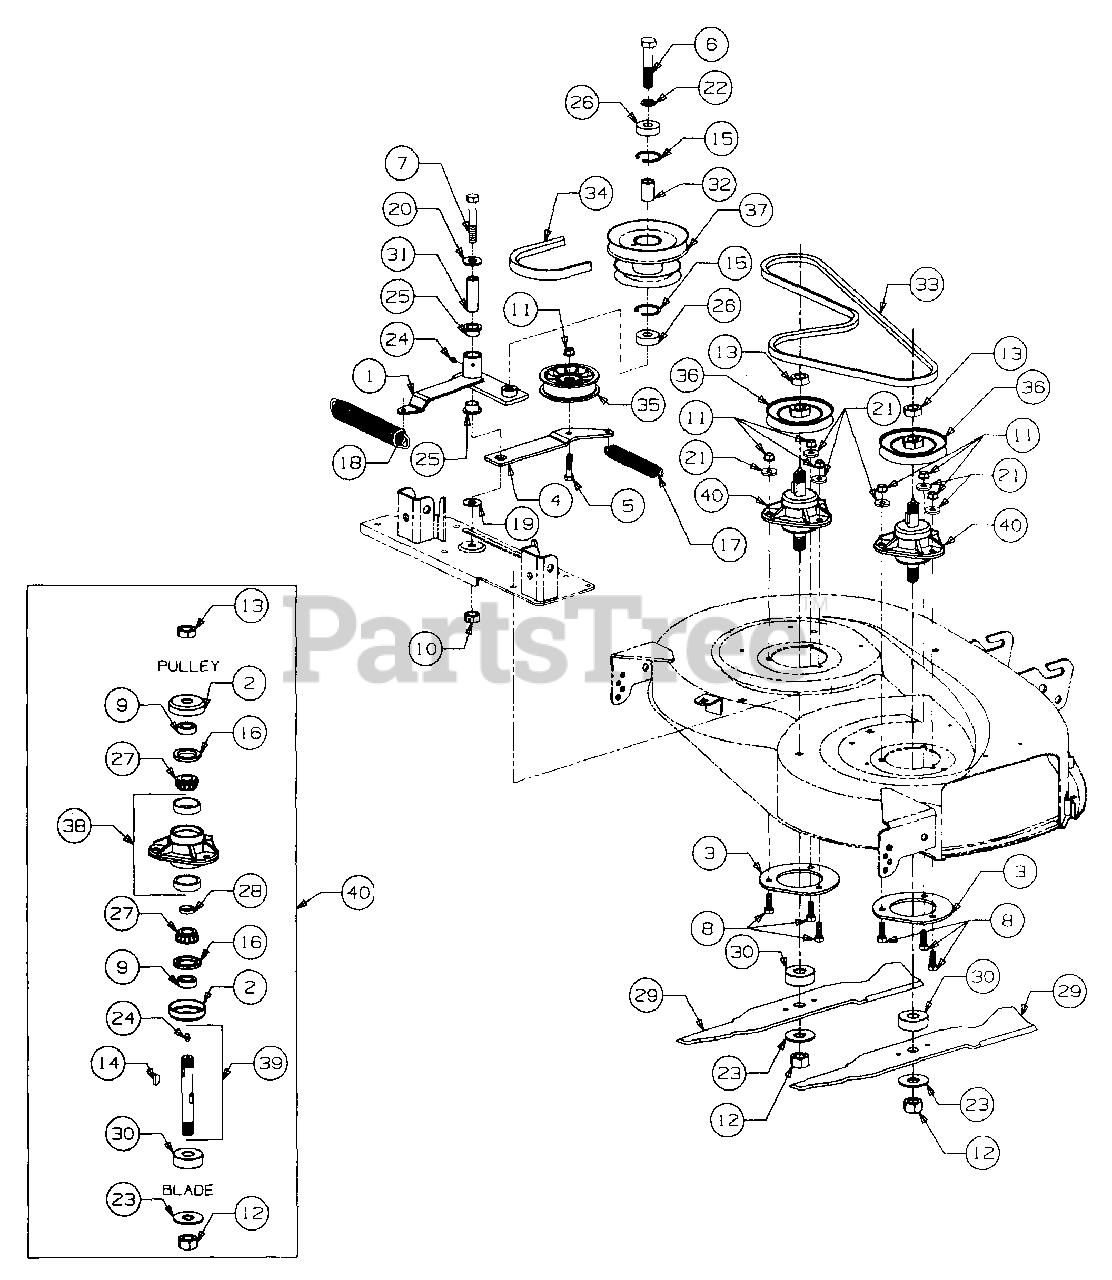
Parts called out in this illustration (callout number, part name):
2	Cup, Spindle Hdn
3	Plate, Spindle Mtg
5	Screw, Hex Cap, 3/8-16 x 1.50 Lg GR5
6	Screw, Hex Cap, 5/8-18 x 3.0 Lg GR5
7	Screw, Hex Cap, 1/2-20 x 3.0 Lg GR8
8	Screw, Hex Cap, 3/8-16 x 1.25 Lg GR5
9	Spacer, .755 x 1.25 x .44 Lg
10	Nut, Hex Center Lock, 1/2-20
11	Nut, Hex Flanged Lock, 3/8-16
12	Nut, Hex, 3/4-16 GR8
13	Nut, Hex Jam, 3/4-16 GR5
14	Key, #91 Woodruff, 1/4 x 3/4 Hdn
15	Snap Ring, Internal
16	Seal, Oil, 1.25 x 1.874 x .25
17	Spring, Extension, .88 OD x 6.12 Lg
18	Spring, Extension, 1.25 OD x 8.15 Lg
19	Washer, Flat, .531 x 1.25 x .036 Thk
20	Washer, Flat, .531 x 1.25 x .100 Thk
21	Washer, Flat, .385 x 1.0 x .135 Thk
22	Washer, Flat, .63 x 1.0 x .063 Thk Hdn
23	Washer, Flat, .781 x 2.0 x .105 Thk
24	Fitting, 3/16 Drive Lube
25	Bearing, Flange, 3/4 ID x .53 Lg
26	Bearing, Ball, .62 ID x 1.57 OD x .44 Thk
27	Cone, Bearing
28	Spacer, Bearing
29	Blade, Low Lift, 19.38 Lg
30	Spacer
31	Spacer, Idler Brkt, .50 ID x .75 OD x 2.25 Lg
32	Spacer, Pulley, .635 ID x .88 OD x 1.25 Lg
33	Belt, Spindle, A-Section x 59 Lg
34	Belt, PTO, B-Section x 112.4 Lg
35	Pulley, Flat Idler, 3.5 OD
36	V-Pulley, 4.62 OD
37	Pulley, Double
38	Housing w/Cups, Spindle
39	Kit, Shaft w/Seal
40	Spindle Assy, Blade
